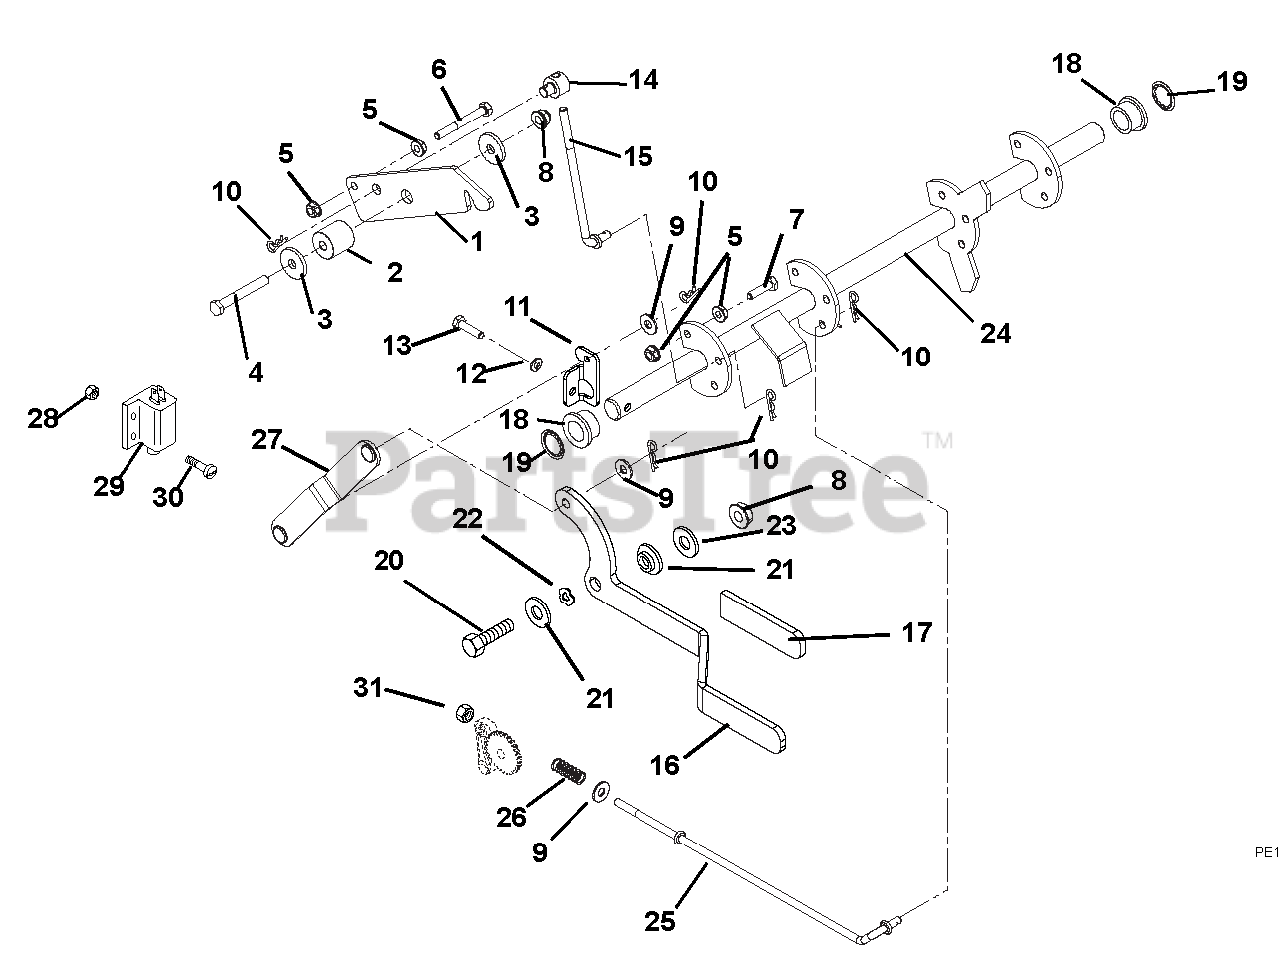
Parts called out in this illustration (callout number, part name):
1	LATCH, NEUTRAL
2	SPCR, FLG .32X.49X.192X1.00
3	WSHR-FL-STL .344X1.125X.135
4	@BLT-HEX .31-18X2.25 GR5 YWZC
5	@NUT-SPNLK-FLG .25-20 YWZC
6	@BLT-HEX .25-20X2.25 GR5 YWZC
7	@BLT-HEX .25-20X1.00 GR5 YWZC
8	@NUT-LK-NYL-FLG .31-18 YWZC
9	@WSHR-FL-STL.312X.734X.065 YWZ
10	PIN-HAIR INT .08X.18X1.18 YWZC
11	CRANK, PARKING BRAKE
12	@WSHR-LK .25X.062 REG YWZC
13	@BLT-HEX .25-20X1.00 GR5 YWZC
14	TRUNNION, BRAKE .31-18 UNC
15	BRAKE LINK
16	HANDLE, PARKING BRAKE
17	GRIP,HANDLE
18	BSHG-FLG .750X1.000X.625X1.250
19	NUT, PUSH -.75" SHAFT
20	@BLT-HEX .31-18X1.75 GR5 YWZC
21	BSHG-FLG .325X.501X.250X1.120
22	WSHR-WAVE .50X.75X.015 .13FRHT
23	WSHR-FL-STL .328X.87X.179 YWZC
24	WELDMENT, BRAKE SHAFT
25	ROD - BRAKE
26	SG-COMP .045X.50X1.187
27	WELDMENT, BRAKE LINK
28	@NUT-LK-NYL 10-24 W/INSRT YWZC
29	SWITCH- DOUBLE POLE N.O./N.O.
30	@SCR-MCH 10-24X.75 HWH YWZC
31	@NUT-LK-NYL .250-20 YWZC
